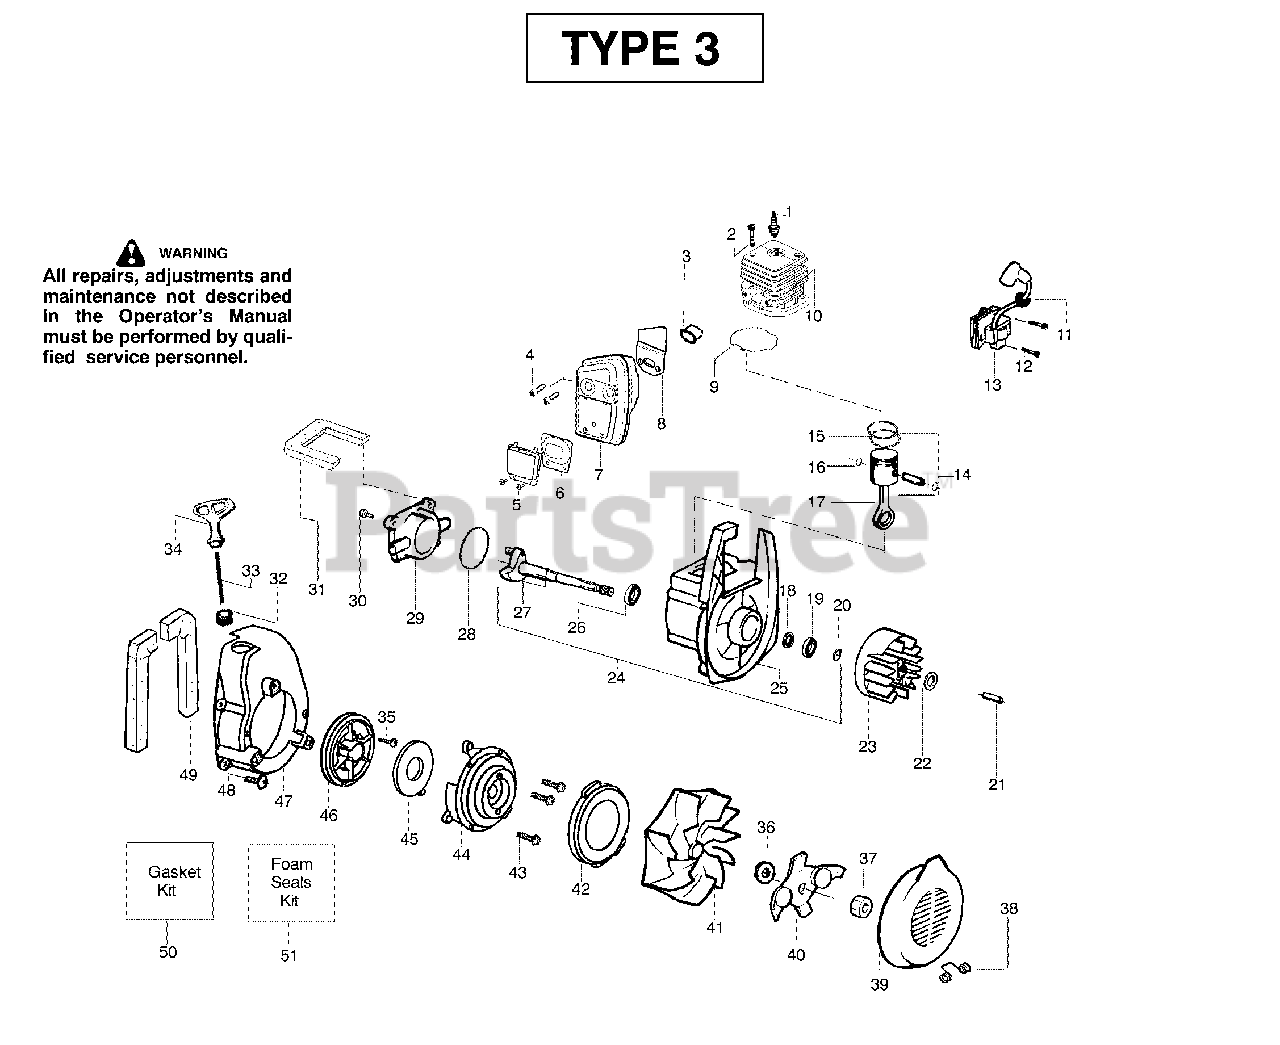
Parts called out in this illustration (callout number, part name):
1	Spark Plug (RCJ-6Y)
3	Insulator-Heat
4	Screw-Muffler-Internal
6	Kit-Spark Screen
7	Kit-Muffler
8	Gasket-Baffle (Kit)
9	Gasket-Cylinder (Kit)
10	Kit-Cylinder
11	Grommet-Ign. Module
12	Screw-Ignition Module
13	Ignition Module
14	Kit-Piston
15	Piston Ring
16	Retainer-Piston Pin
17	Assy-Connecting Rod
18	Seal-Crankcase
19	Bearing-Outer
20	Retainer Ring-C'chaft
21	Spacer-Flywheel
23	Assy-Flywheel
24	Assy-Crankcase/Crankshaft
25	Assy-Crankcase
26	Bearing-Inner
27	Assy-Crankshaft
28	O-ring-C/case (Kit)
29	Cover-Crankcase
30	Screw
31	Foam-219mm (Kit)
32	Eyelet-Flange
33	Kit-Rope
34	Handle-Starter
35	Screw-Rope
36	Washer-Belleville
38	Spring-Return Cover
39	Inlet Door
40	Assy-Mulch Blade
41	Assy-Impeller
42	Seal-Ring
44	Housing-Pulley
45	Spring-Starter
46	Kit-Starter Pulley
47	Fan Housing
48	Screw
49	Foam-182mm (Kit)
50	Kit-Gasket
51	Kit-Foam Seals
